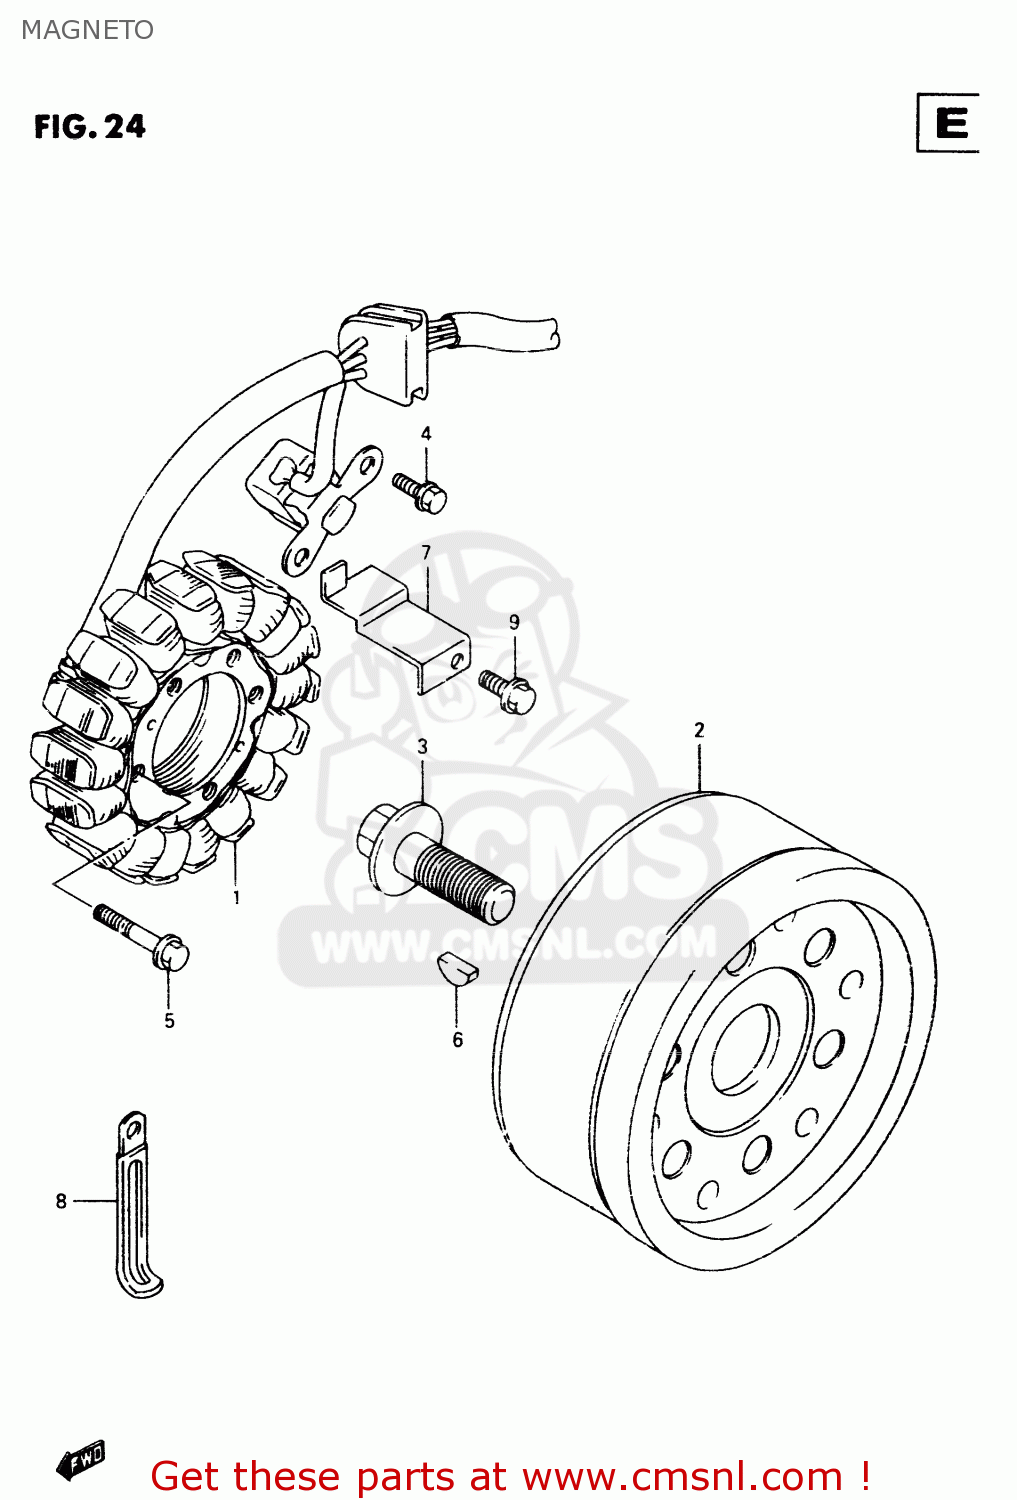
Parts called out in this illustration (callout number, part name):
1	STARTER ASSY
2	ROTOR ASSEMBLY
3	BOLT(14X43)
4	BOLT
5	BOLT,G/S SWITC
6	KEY
7	CLAMP,MAGNETO LEAD WIRE
8	CLAMP(L:45)
9	BOLT
